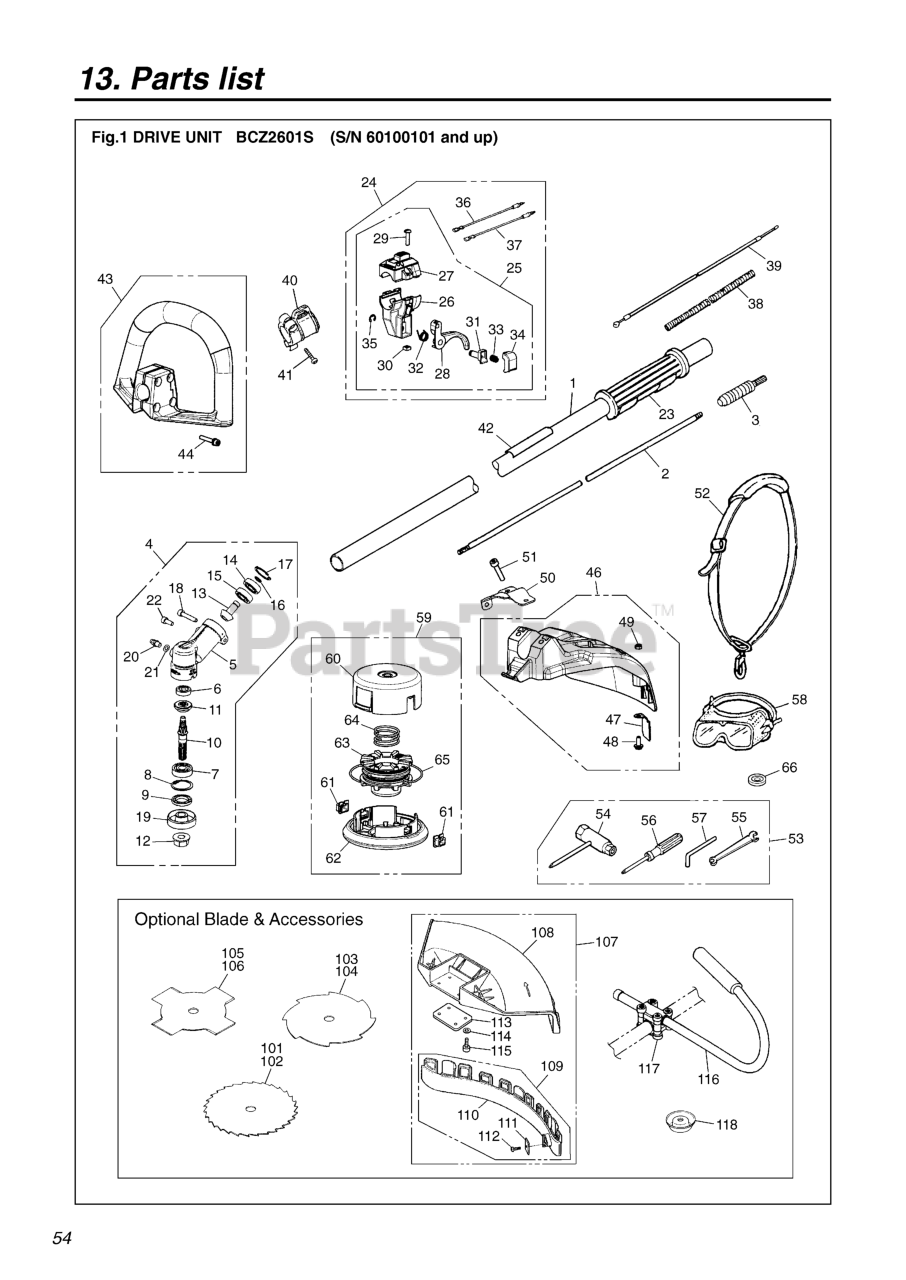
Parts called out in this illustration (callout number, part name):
1	PIPE COMP.
2	SHAFT
3	JOINT COMP.
4	GEARCASE ASSY
5	GEARCASE
8	RING, SNAP, M26 X 1.2
9	SEAL, OIL
10	SHAFT
11	GEAR
12	NUT
13	PINION
17	RING, SNAP, M24 x 1.2
18	BOLT, TORX
19	HOLDER (A)
20	FITTING, GREASE
21	WASHER, M6 X .8
22	BOLT, TORX
23	GRIP
24	LEVER ASSY
25	LEVER
27	COVER COMP. (RP. 6110-14410-02)
28	FLEX, TRIGGER
36	CORD (A), BLACK
37	CORD (B), RED
38	TUBE (RPLS 4900-72141)
39	CABLE (RPLS 5580-83100)
40	HANGER COMP.
41	SCREW
42	LABEL NAME & CAUTION
43	HANDLE ASSY. (REPLACES -14001)
44	SCREW
46	GUARD COMP.
47	BLADE (RPLS T3002-24120)
48	SCREW TORX
49	NUT
50	BRACKET
51	BOLT, TORX
52	STRAP ASSY. (USE 848-JC0-3610)
54	SOCKET
55	SPANNER, 8 X 10 (RPLS 2540- )
56	SCREWDRIVER
57	BAR
58	GOGGLE
59	TAP HEAD COMP.
60	CASE (REPLACES -15111)
61	EYELET
62	COVER (REPLACES -15131)
63	HOLDER, CORD (REPLACES-15141)
64	SPRING
65	CORD
66	HOLDER (B)
101	BLADE, 9
102	BLADE, 9
103	BLADE, 8
104	BLADE, 9
105	BLADE, 8
106	BLADE, 9
107	GUARD ASSEMBLY
108	GUARD
109	PLATE COMPLETE
110	PLATE
111	BLADE
113	PLATE
114	WASHER, SPRING M4 x 1.3
115	BOLT, M5 X 16
116	HANDLE, J
117	BRACKET ASSY (REPLACES -14100)
118	COVER
